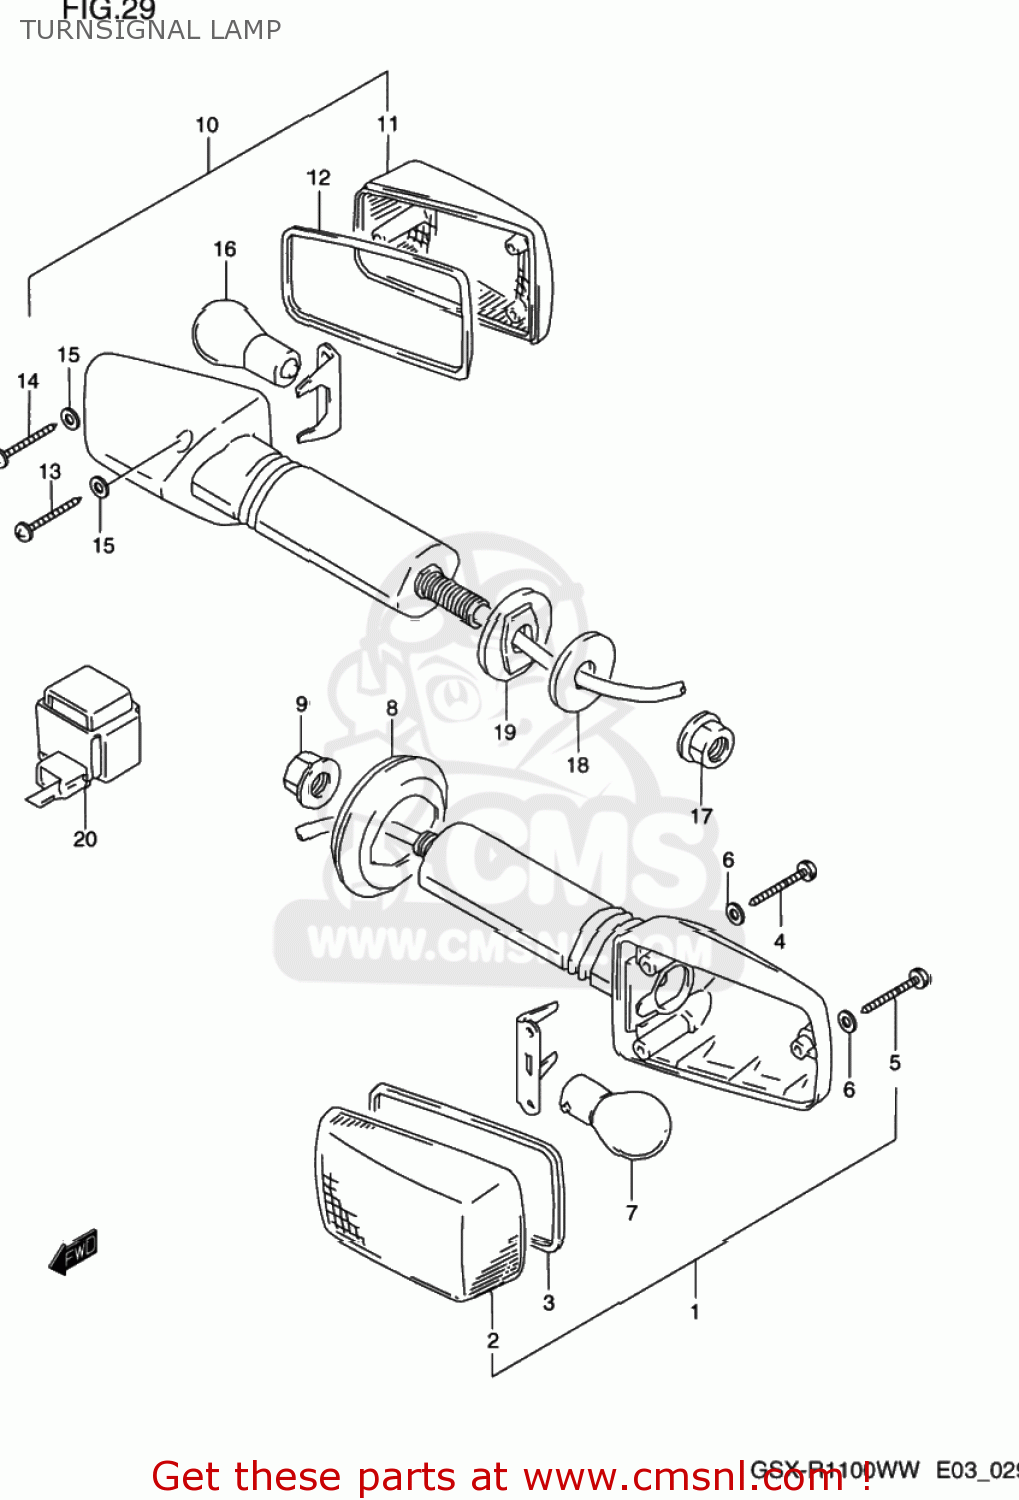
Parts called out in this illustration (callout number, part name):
1	LAMP ASSY,FR TURN SIGNAL
2	LENS
3	GASKET (NAS)
4	SCREW(3X30)
5	SCREW
6	GASKET (NAS)
7	BULB(12V21W)
8	GROMMET
9	NUT
10	LAMP ASSY,RR TURNSIGNAL
11	LENS
12	GASKET (NAS)
13	SCREW(3X30)
14	SCREW
15	GASKET (NAS)
16	BULB(12V21W)
17	NUT
18	WASHER(10.5X30X3.2)
19	SPACER,RR TURNSIGNAL
20	RELAY ASSY
